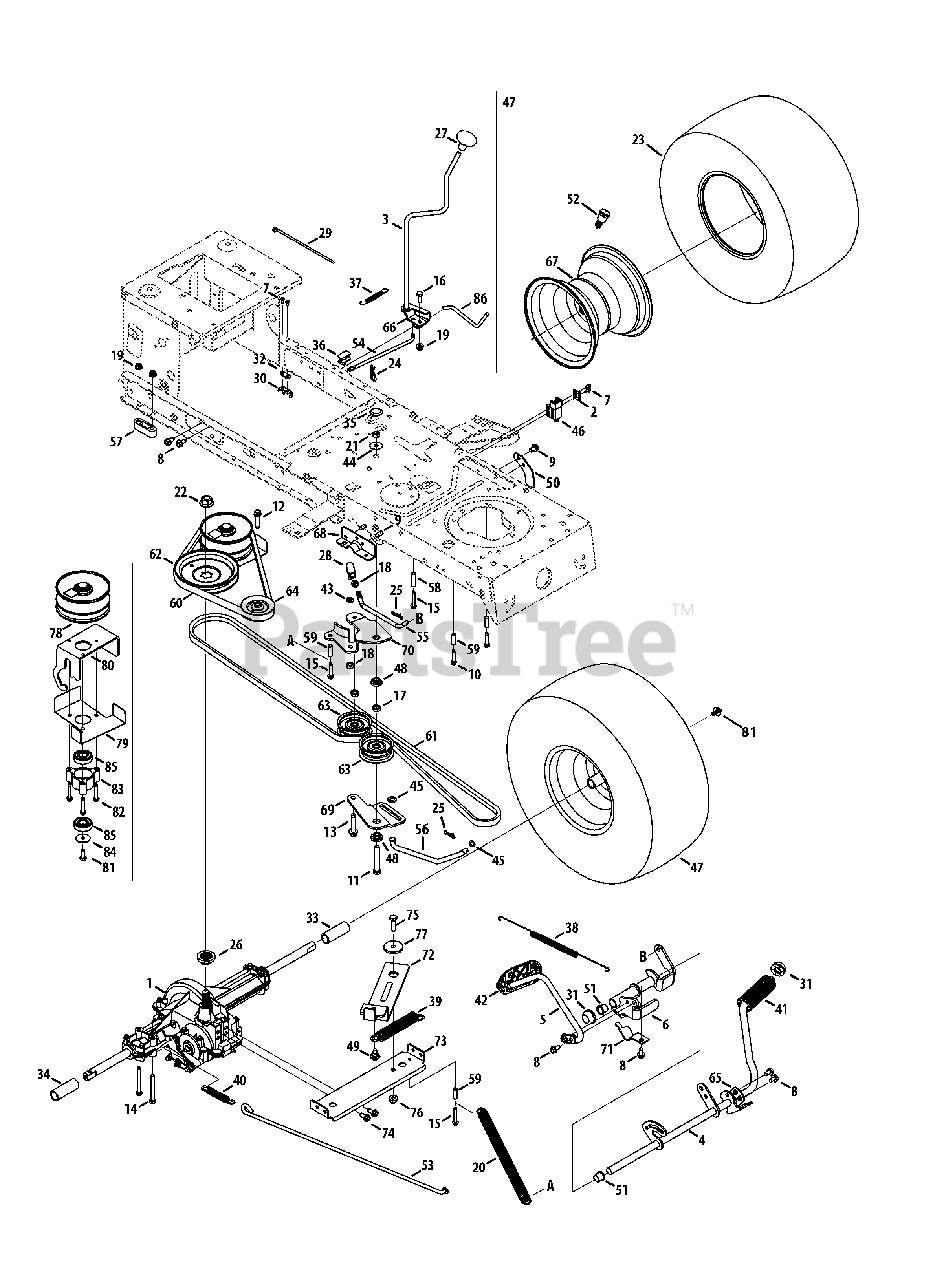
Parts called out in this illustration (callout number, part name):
1	Transmission Drive Assembly
2	Plate Switch
3	Shaft Lever Assembly
4	Pedal Assembly, drive
5	Pedal Assembly, control
6	Pedal Bracket Assembly
7	Screw, 8-18:0.500
8	Screw, 5/16-18 x .750
9	Screw, 5/16-18 x 0.625
10	Screw, 1/4-20 x 1.250
11	Hex Screw, 3/8-16 x 2.50
12	Screw, 3/8-16 x 1.500
13	Screw, 3/8-16 x 1.750
14	Hex Screw, 5/16-18 x .625
15	Screw, 1/4-20 x 1.75
16	Hex Screw, 5/16-18 x .75
17	Jam Nut, 7/16-20
18	Hex Nut, 3/8-24
19	Flangelock Nut, 5/16-18
20	Spring Extension, .56 OD x 12.05
21	Nut, 3/8-16, Centerlock
22	Flange Nut, 9/16-18
23	Tire, 20 x 8 x 8, 42" Deck
24	Cotter Pin INT- .125 DIA
25	Bow-Tie Cotter Pin, 72
26	Pulley Hub, 5/8 SPLINE
27	Shift Knob
28	Ball joint
29	Cable tie
30	Short Spring Switch
31	Push Cap, 5/8
32	Plate Insulator Nut
33	Sleeve, .758 x .821 x 3.3125
34	Sleeve, .758 x .821 x 2.4375
35	Plug, 7/8
36	Shift Plate Bearing
37	Spring Extension, .38 OD x 3.25 LG
38	Spring Extension, .70 OD X 12.00
39	Spring Extension, .97 Od X 6.18 Lg
40	Spring Extension, .59 OD x 4.00 LG
41	Foot Pad, 4.0 Long
42	Control Pad
43	Lock Washer 3/8
44	Flat Washer, .406 x 1.920 x .060
45	Flat Washer, .375 X .738 X .063
46	Switch Interlock
47	Wheel, 20 x 8 x 8, 42" Deck
48	Shoulder Spacer, 1.00 X .38 X .38
49	Shoulder Screw, .43 x .29, 5/16-18
50	Stop Pedal Plate
51	Flng Bearing .63 Id x .695 Od X .60
52	Valve, tubeless Air
53	Brake Rod
54	Shift Rod, 46"
55	Idler Adjustment Rod
56	Transmission Bypass Rod
57	Spacer, T-Axle .68
58	Spacer, .260 X .372 X 1.420 Lg
59	Spacer, .260 X .375 X 1.030 Lg
60	V Belt, 5L 40.9 Poly
61	V Belt, 5L, 90.93 Poly
62	V Pulley 7.25 DIA SPUN
63	Idler Pulley
64	Idler Pulley
65	Pedal Support Bracket
66	Shaft Adjust Bracket
67	Rim, 8.0 X 7.0 X .750, 46" Deck
68	Frame Pedal Bracket, Rh
69	Center Idler Bracket
70	Idler Bracket
71	Pedal Support Bracket
72	Idler Bracket Assembly
73	Bracket Assembly
74	Screw, 5/16-18 x 0.750
75	Hex Screw, 3/8-16 x 1.25
76	Flangelock Nut, 3/8-16
77	Shoulder Spacer, .8840 X .190
78	Variable Speed Pulley Assembly
79	Belt Keepr Assembly
80	Bracket Assembly
81	Screw, 5/16-24 x .750
82	Screw, 1/4-20 x 1.500
83	Bearing Cup
84	Flat Washer, .330 X 1.25 X .06
85	Ball Bearing, 17 x 40 x 12
86	Spring Retainer Rod
